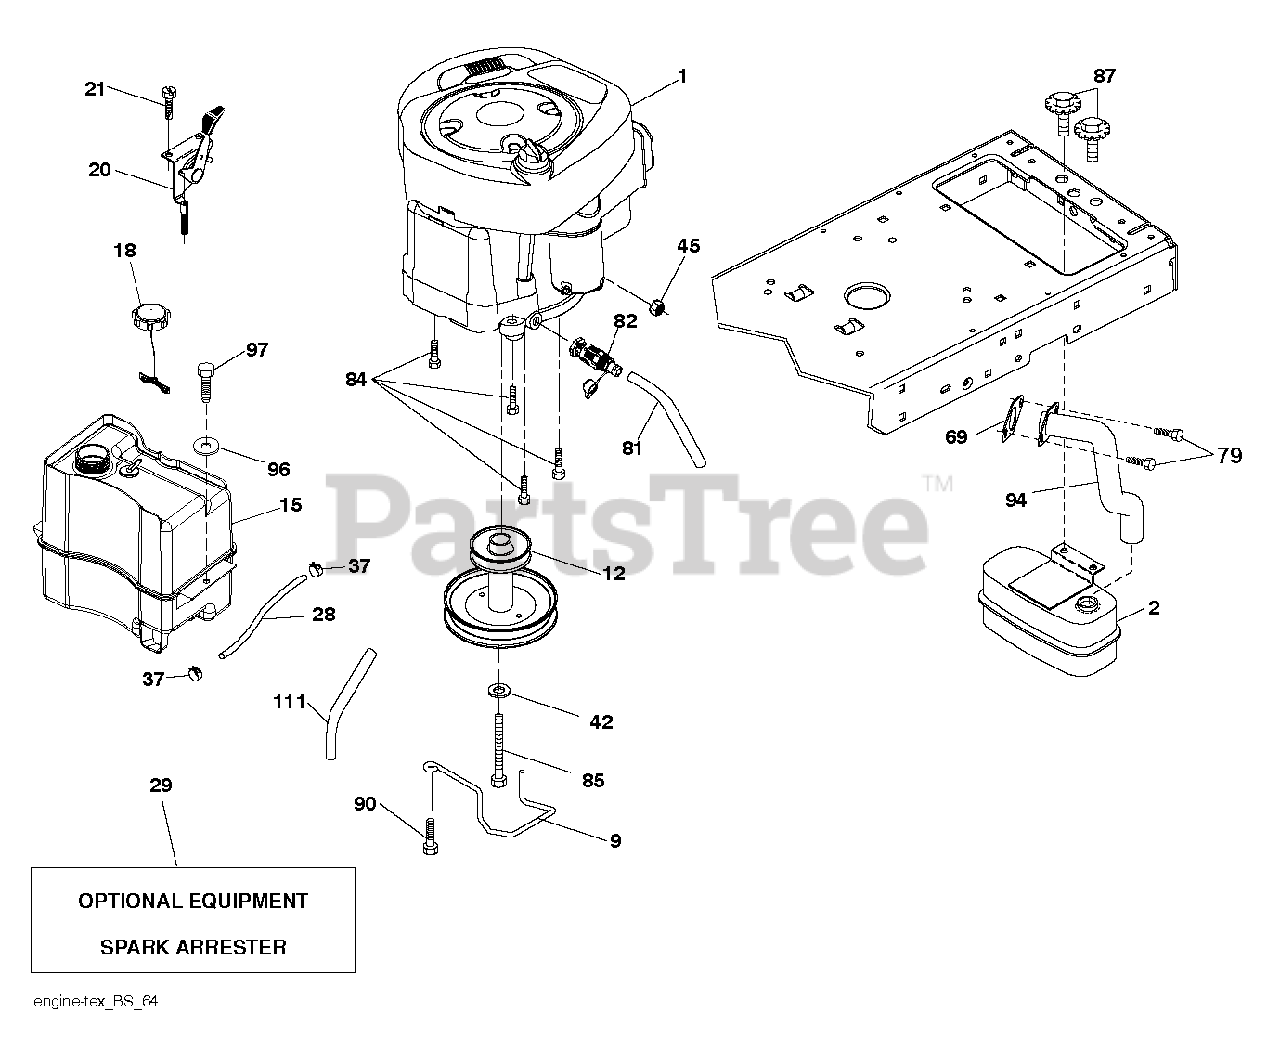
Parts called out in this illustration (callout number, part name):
2	MUFFLER.SINGLE.LRG.BRIGGS.KOHL
9	KEEPER BELT ENGINE
12	Engine Pulley
15	TANK.ASM.FRT.2.5 GAL.W/CAP.EPA
18	CAP.FUEL.2 WAY VENT
20	THROTTLE.COBRA.21".RSTART.BLK
21	SCREW.#10 X 0.750.BOS (2 2)
28	LINE.FUEL.20"FRONT.EMI
29	KIT.SPARK ARRESTOR(392390 B&S)
37	HOSE CLAMP
42	LOCKWASHER
45	NUT
79	SCREW.SOCKET HD.5/16-1
81	TUBE, DRAIN OIL ASM.
82	VALUE.OIL.DRAIN
84	SCREW.3/8-16
85	BOLT HEX 7/16-20X4-1/4"
87	BOLT, 5/16-18 X 1 3/4
90	SCREW 3/8-16X1
94	Exhaust Tube, B&S 28/31
97	SCREW HEXWSHR 1/4-20X3/4
111	RP PURGE LINE
